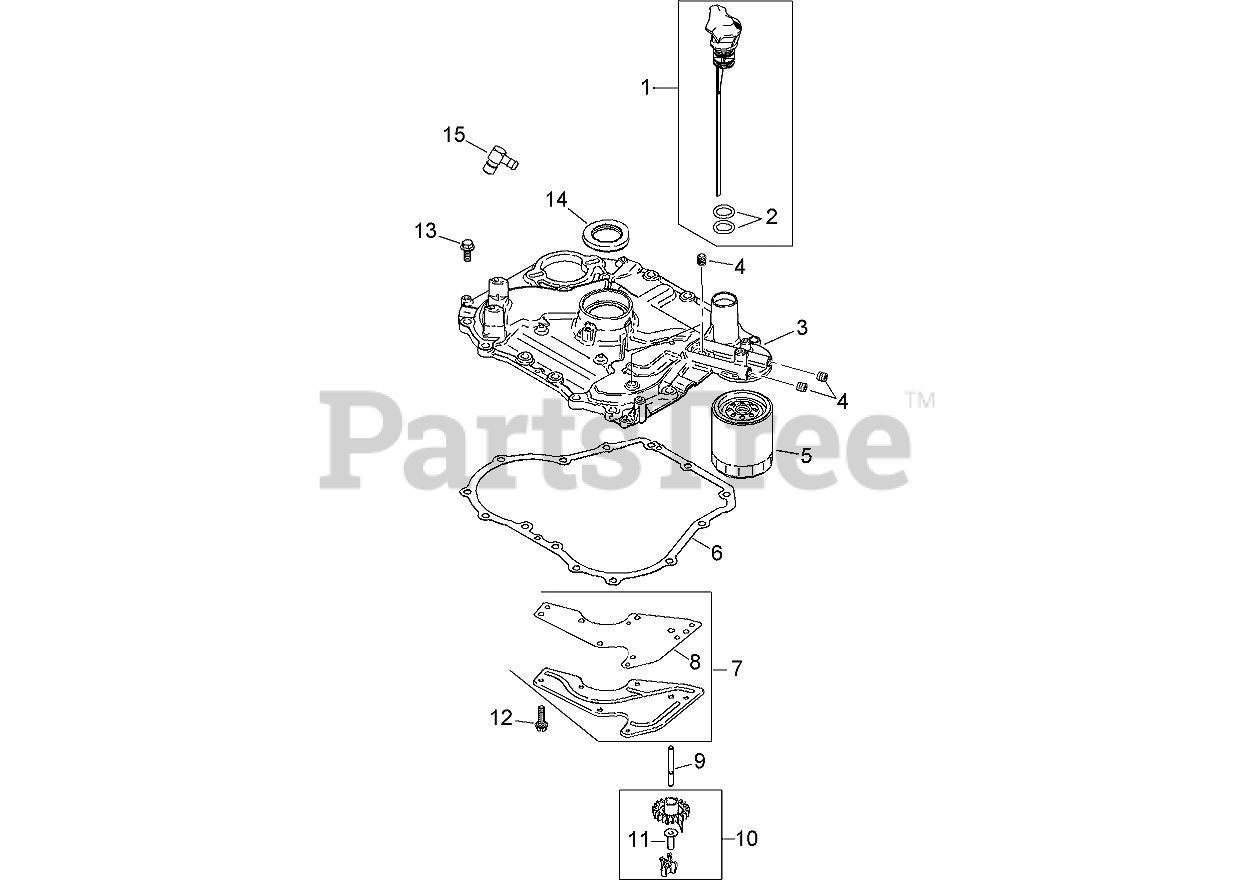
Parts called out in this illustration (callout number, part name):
1	DIPSTICK BLADE KIT (YELLOW)
2	O-RING
3	CLOSURE PLATE ASM
4	PLUG-PIPE, COUNTERSUNK (1/8)
5	FILTER-OIL
6	Gasket-Plate, Closure
7	Oil Passage Cover Kit
8	Gasket-Passage, Oil
9	Shaft-Gear, Governor
10	GOVERNOR GEAR ASM
11	PIN-REGULATING, GOVERNOR
12	SCREW-FLG, THD FRM (M5X0.8X13)
13	SCREW-FLANGE, HEX (1/2 DOG POINT)
14	Seal-Oil
15	Connector-Hose, 90 Deg
